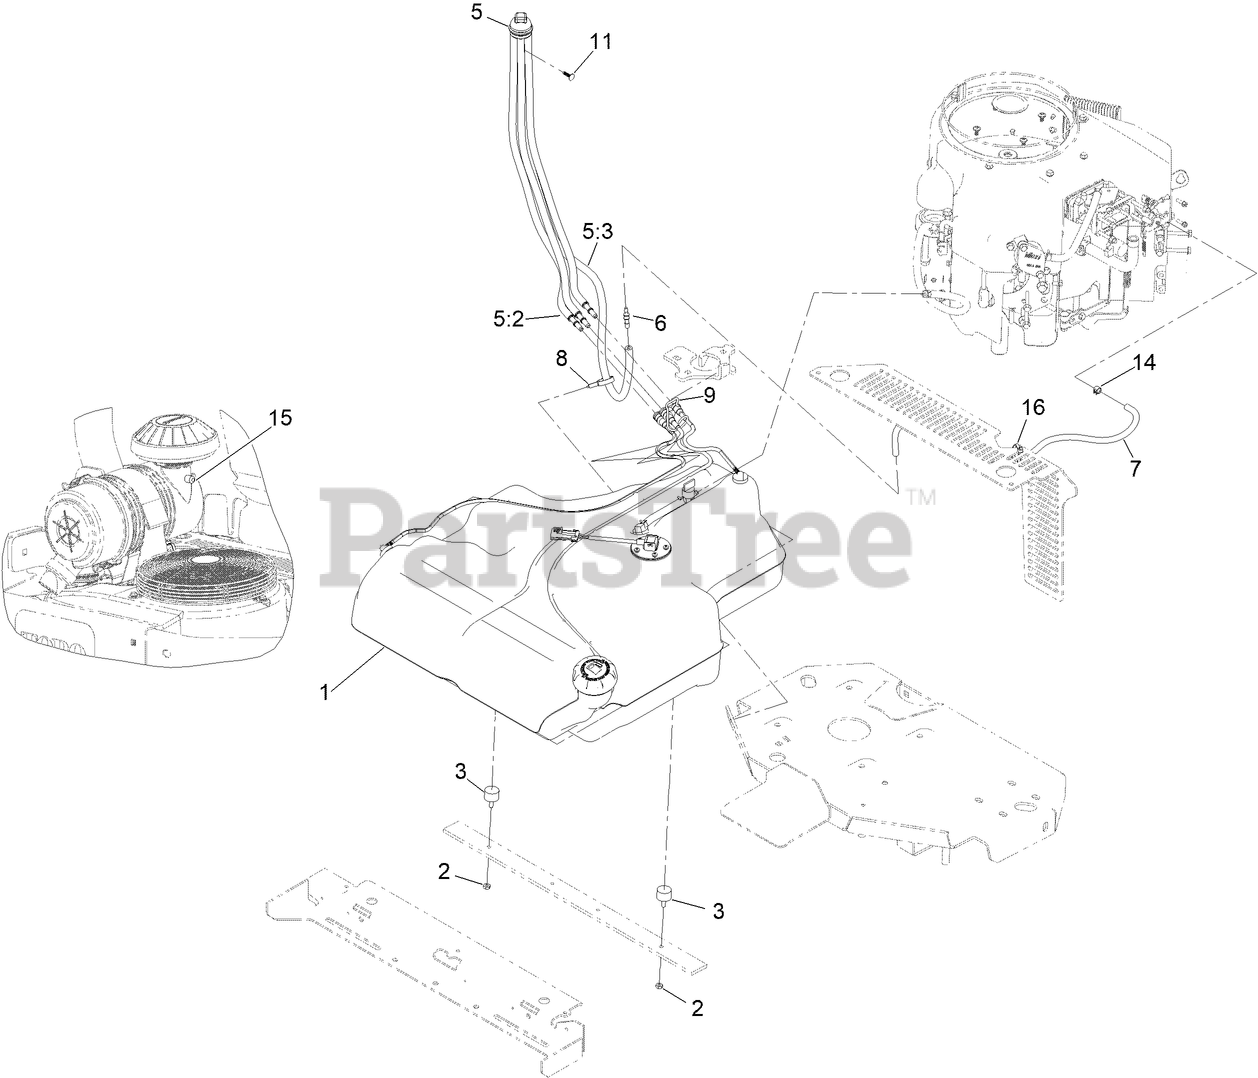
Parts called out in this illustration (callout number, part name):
1	FUEL TANK ASM
2	NUT-JAM
3	BUMPER
5	FUEL MANIFOLD VENT ASM
5:2	HOSE-FUEL
5:3	HOSE-FUEL
6	BARB-FUEL
7	HOSE-FUEL
8	CLAMP-HOSE
9	RETAINER-LINE, VAPOR
11	PLUG-PLASTIC
14	CLAMP-HOSE
15	PLUG-PORT
16	TIE-CABLE
